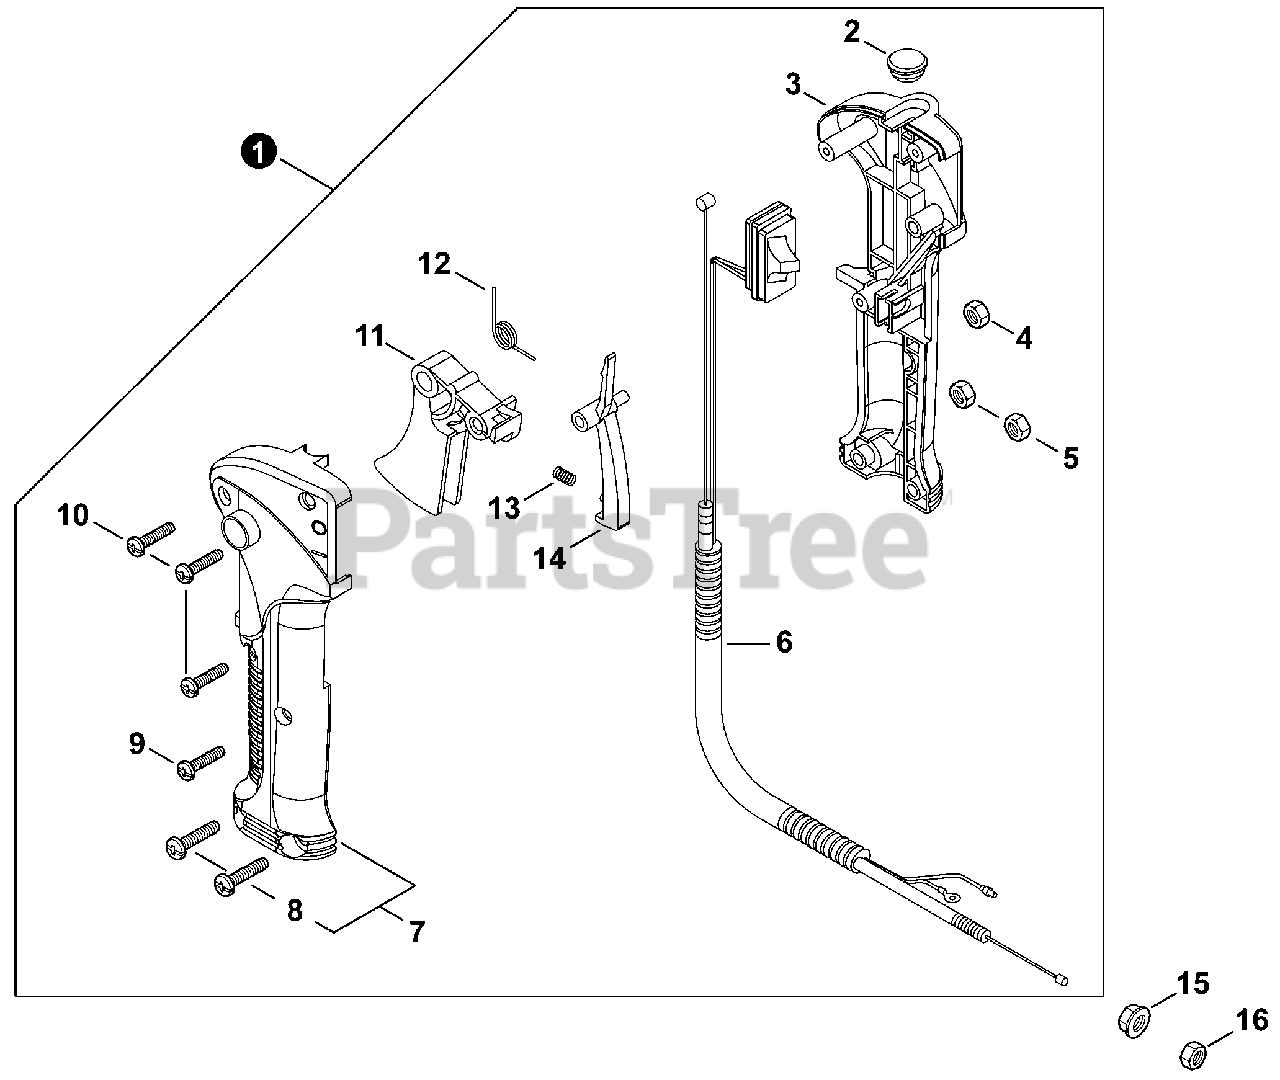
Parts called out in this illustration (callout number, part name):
1	THROTTLE CONTROL ASSY
2	PLUG, RUBBER
3	CONTROL HANDLE - RIGHT
6	CABLE ASSY, CONTROL
7	CONTROL HANDLE KIT
8	SCREW M5×22
9	SCREW M4×23
10	SCREW, TAPPING 4×16
11	TRIGGER, THROTTLE
12	SPRING, TORSION
13	SPRING, COMPRESSION
14	LOCKOUT, THROTTLE
15	NUT, FLANGE M6
